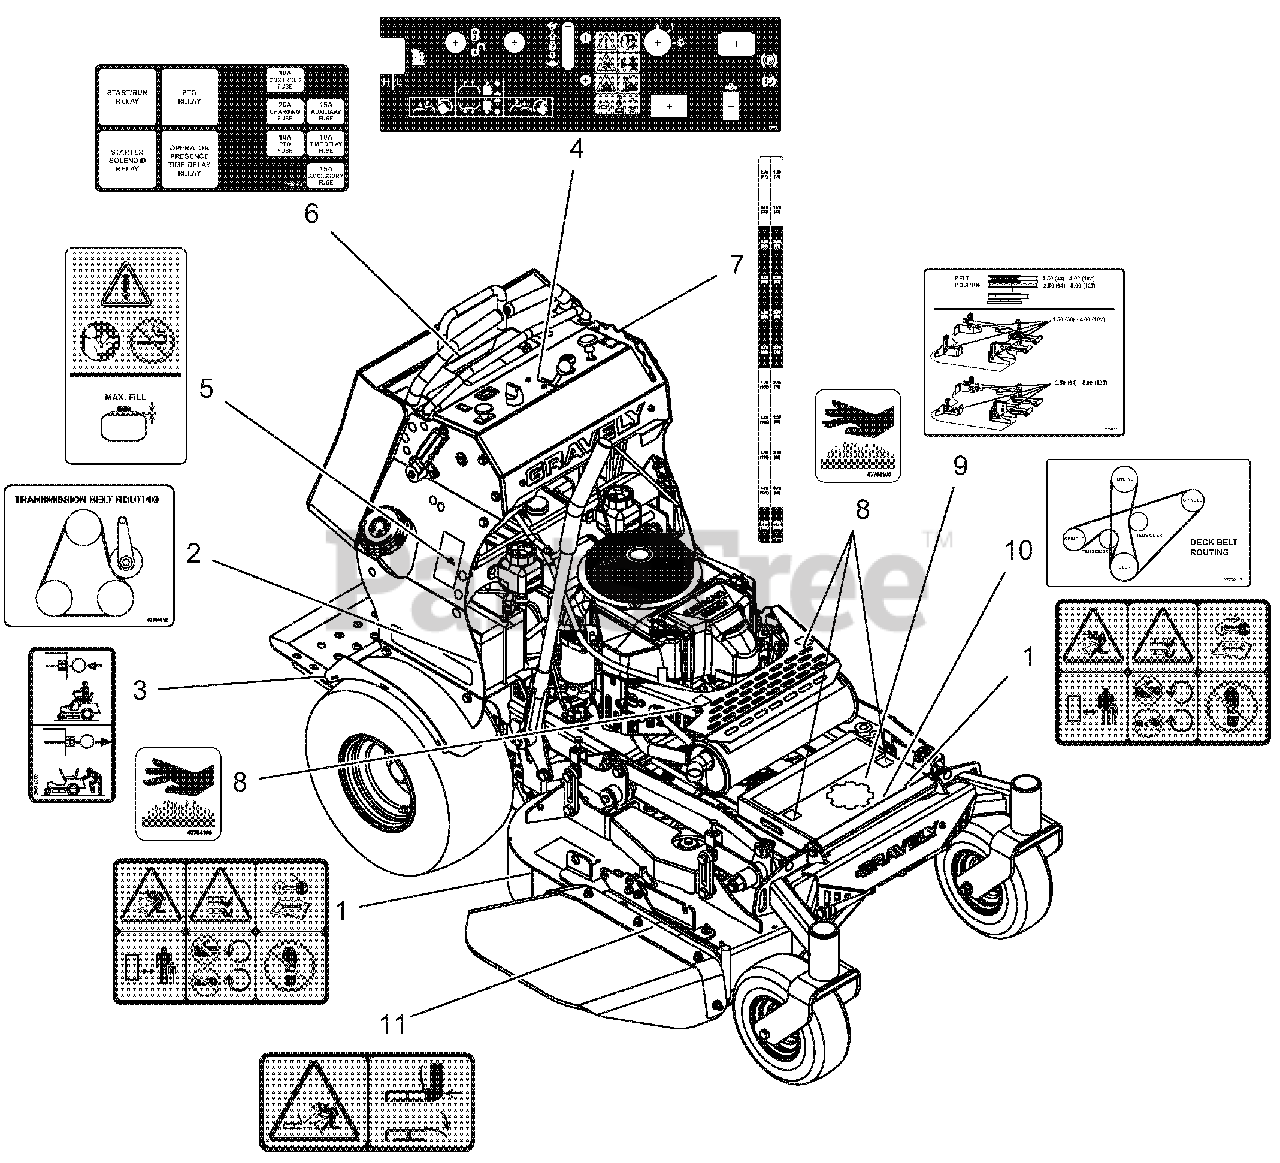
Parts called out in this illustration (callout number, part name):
1	DECAL, SAFETY - MOWER DECK
2	DECAL, HYDRO BELT ROUTING
3	DECAL, TRANSMISSION DISCONNECT
4	DECAL, CONTROL PANEL
5	DECAL, FUEL Warning
6	DECAL, FUSE BLOCK
7	DECAL, HOC DIAL
8	DECAL HOT SURFACE
9	DECAL, BELT POSITIONING
10	DECAL, BELT ROUTING
11	DECAL, SAFETY - DECK GUARDING
